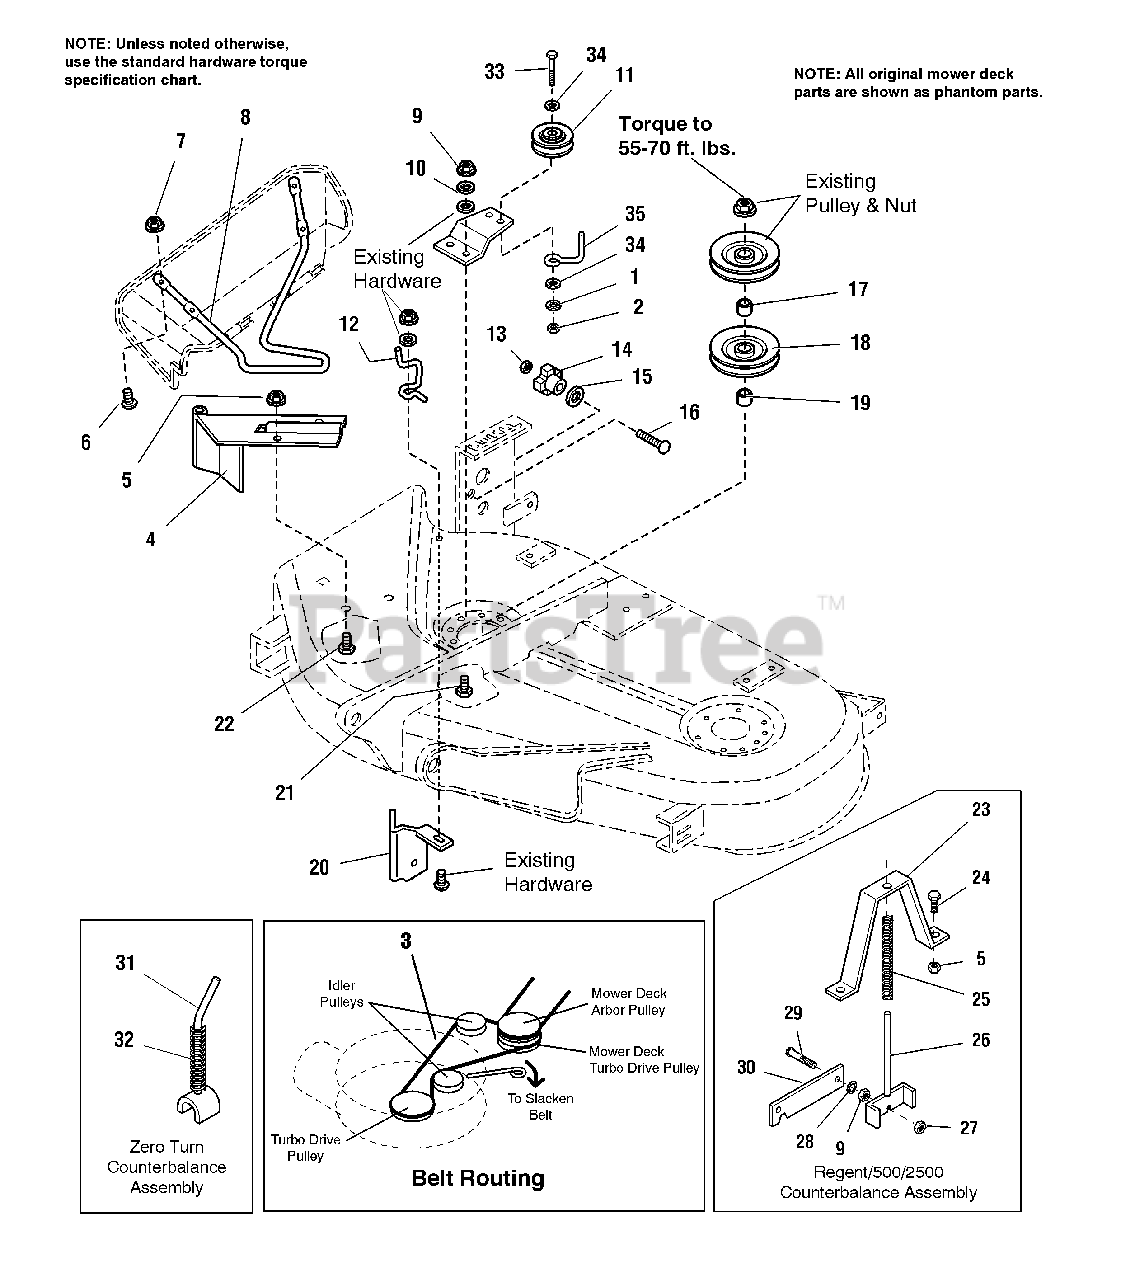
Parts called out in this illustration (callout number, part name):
1	LOCKWASHER, 3/8
2	NUT, 3/8-16
4	PIVOT BRACKET
5	LOCKNUT, 5/16-18
6	SCREW, Truss Hd., 10-24 x 3/4
7	NUT, Nylock, 20-24
8	SUPPORT ROD, Deflector
9	NUT, 5/16-18
10	LOCKWASHER
11	IDLER PULLEY ASSY.
12	SPRING LATCH
13	LOCKNUT, 5/16-18
15	WASHER, 11/32 OD x 1-1/4 ID x 1/8 Thick
16	CARRIAGE BOLT, 5/16-18 x 1-1/2
17	HUB, Splined, 1.28" Long
19	HUB, 1.65" Long
21	SCREW, Taptite, 5/16-18 x 1-1/2
22	CARRIAGE BOLT, 5/16-18 x 3/4
23	BRACKET, Counterbalance
24	SCREW, Hex Whiz-Lock, 5/16-18 x 3/4
25	SPRING, Compression (Long)
26	ROD ASSEMBLY, Counterbalance
27	NUT, Flange, 2-Way Lock, 5/16-18
28	LOCKWASHER, 5/16
29	CARRIAGE BOLT, 5/16-18 x 1-1/4
31	LEVER ASSEMBLY, ZT Counterbalance
32	SPRING, Compression (Short)
33	CAPSCREW, 3/8-16 x 1-1/4
34	WASHER, 3/8
